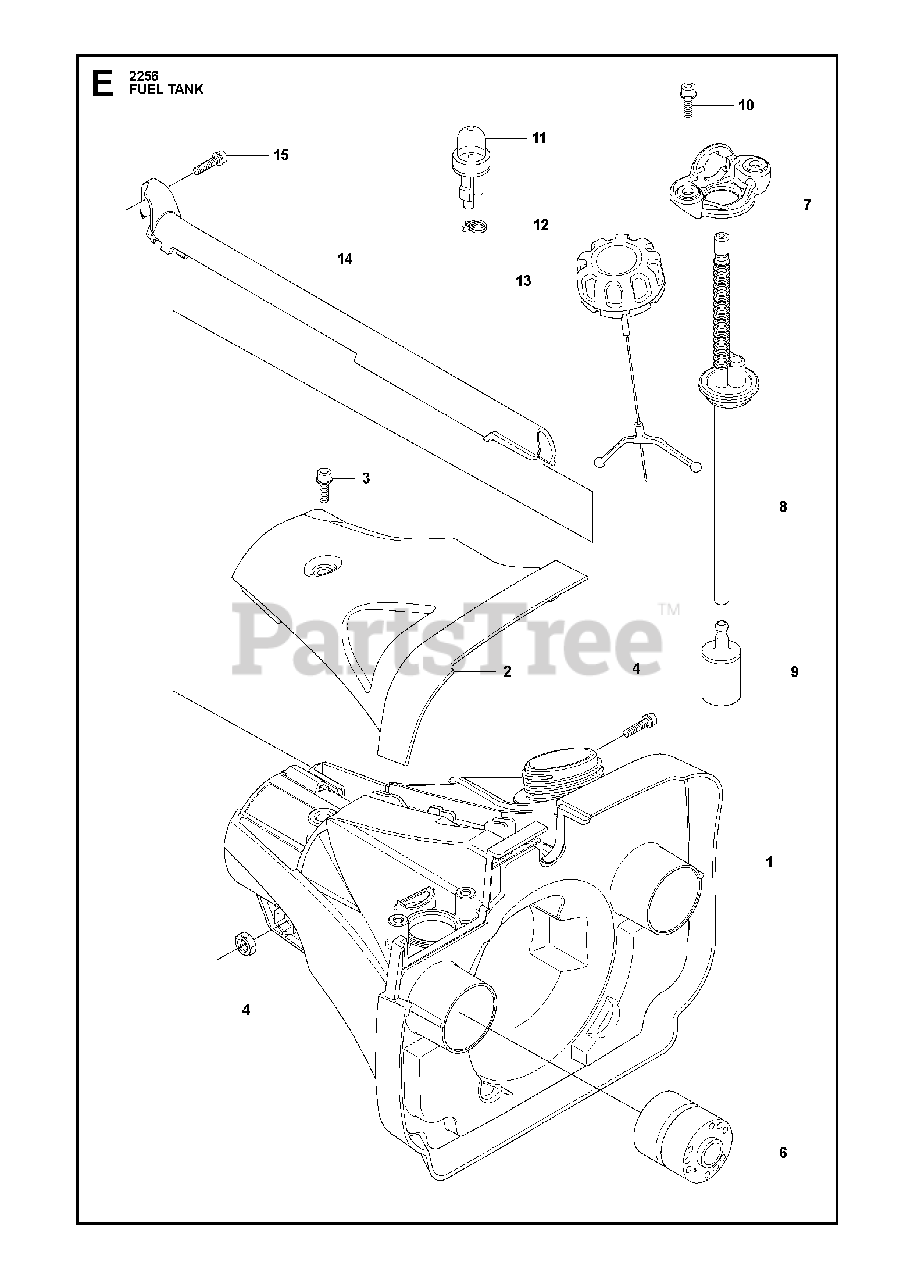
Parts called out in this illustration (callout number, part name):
3	SCREW IHSCFM
6	ANTIVIBE ELEMENT
8	FUEL HOSE
9	FUEL FILTER
11	AIR PURGE BUBBLE
12	HOSE CLAMP
15	SCREW IHSCFM
